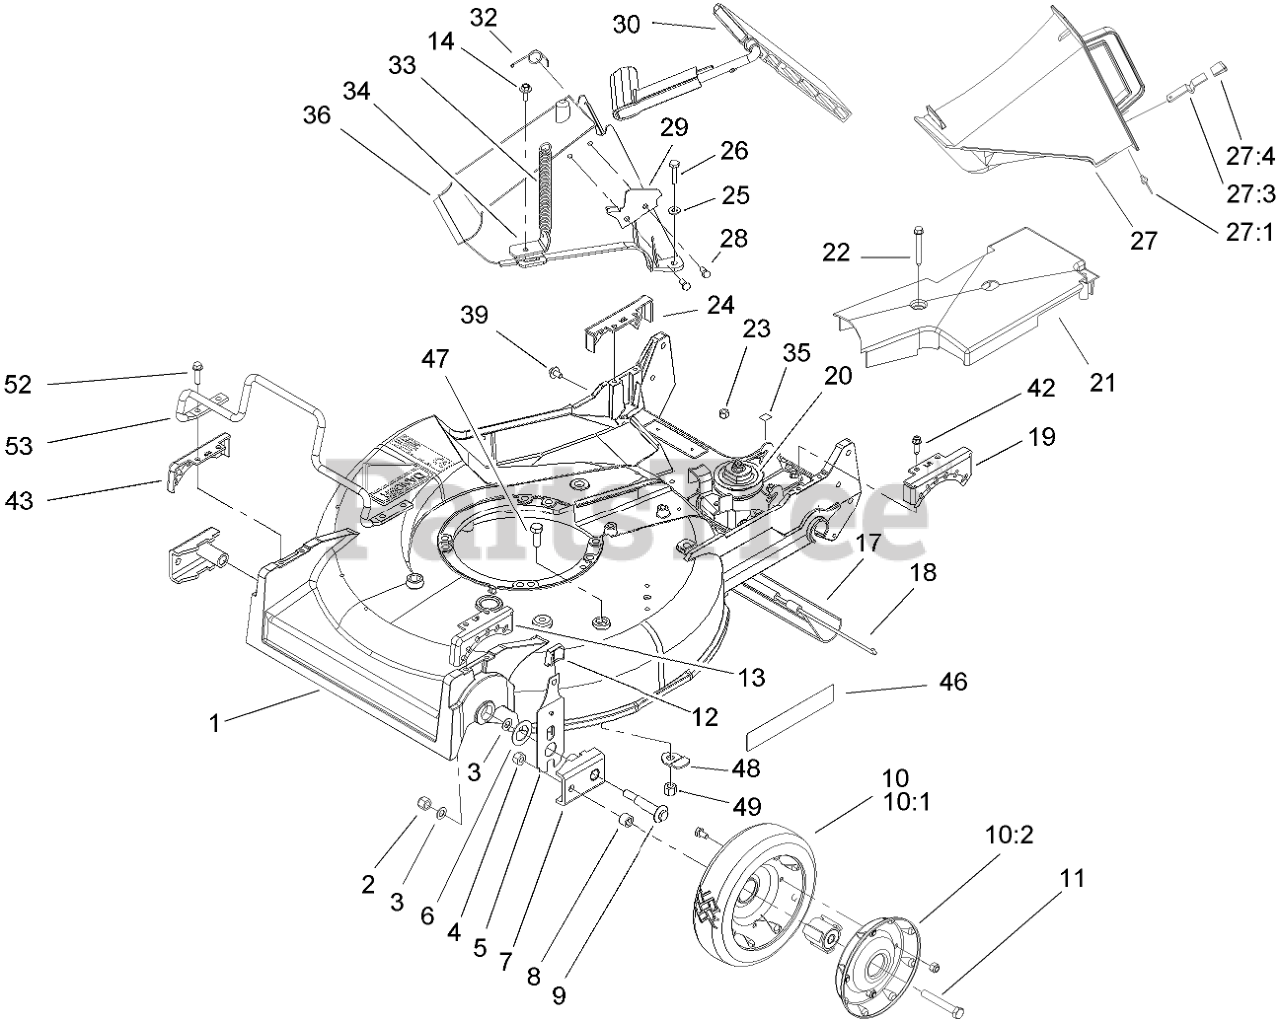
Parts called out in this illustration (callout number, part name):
1	HOUSING
2	NUT-LOCK
3	WASHER
4	NUT-LOCK, CONE
5	FRONT SPRING ARM ASM
6	WASHER-THRUST
7	ARM-PIVOT, FRONT
8	SPACER-WHEEL
9	BOLT-WHEEL
10	Wheel and Tire ASM
10:2	Wheel ASM
11	SCREW-HH
12	KNOB-ARM
13	QUADRANT-FRONT, LH
14	SCREW-HWH
17	SHIELD-TRAILING
18	ROD-SHIELD
19	QUADRANT-REAR, LH
20	GEAR CASE ASM
21	COVER-BELT
22	SCREW-HHFTF
23	NUT-LOCK, NI
24	QUADRANT-REAR, RH
25	WASHER-FLAT
26	SCREW-HH
27	DISCHARGE PLUG ASM
27:1	RIVET-HEAD, FLAT
27:3	LATCH-PLUG, DISCHARGE
27:4	GRIP-LATCH
28	SCREW-PLASTITE
29	LATCH-PLATE
30	DISCHARGE DOOR ASM
32	RETAINER-DOOR
33	SPRING-DOOR
34	BRACKET-SPRING
35	DECAL-GREASE
36	TUNNEL-DISCHARGE
39	SCREW AND WASHER ASM
42	SCREW-HWHTF
43	QUADRANT-FRONT, RH
47	SCREW-HH
48	SHIELD-RETAINER
49	NUT-LOCK, NI
52	SCREW-HWHTF
53	GUARD-ENGINE
